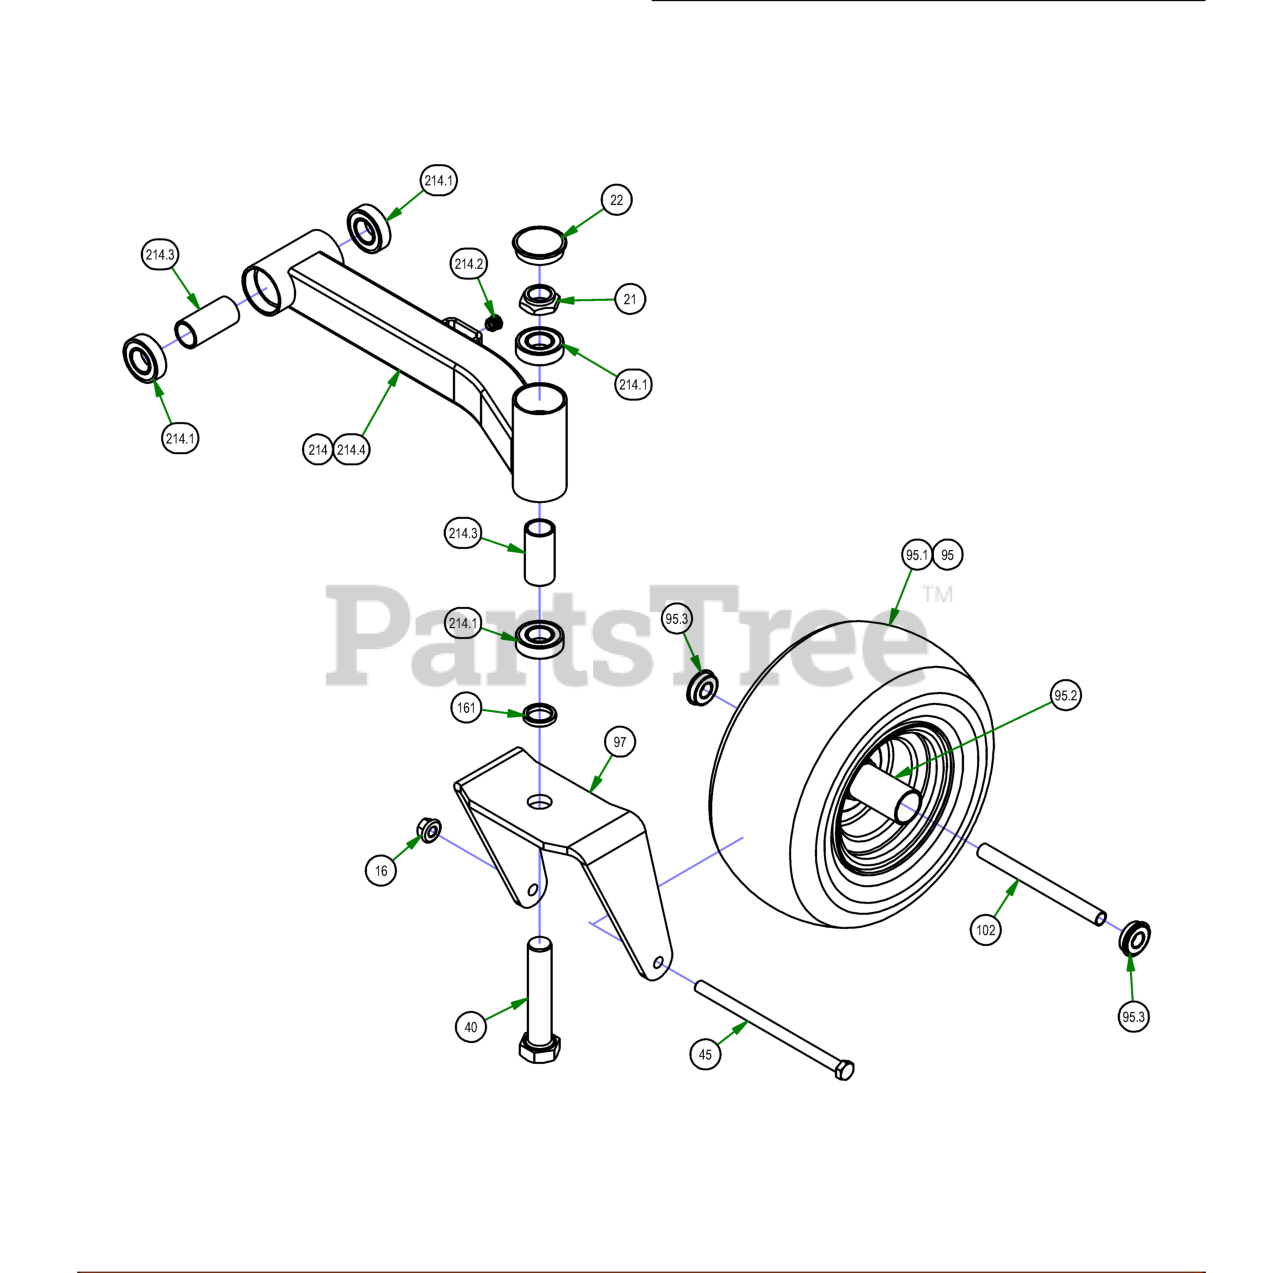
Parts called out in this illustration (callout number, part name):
16	1/2-13 NYLON INSERT FLANGE LOCKNUT ZINC
21	1"-14 NYLON INSERT JAM LOCKNUT ZINC
22	2017 Bearing Cover
40	1"-14 X 5 HEX CAP SCREW (GR.8) ZINC YELLOW
45	1/2-13 X 8-1/2 HEX CAP SCREW (GR.5) ZINC
95	13x6.5-6 Black Tire and Wheel Assembly
95.1	13 x 6.50 - 6 Tire
95.2	Front Tire Rim
95.3	Ball Bearing w/Retainer, 99502H-NR, .625 Bore x 1.375 OD x .4375 Width
97	2017 ZT Front Fork
102	Front Wheel Spanner
161	Spacer, 1x1.375x.25
214	2021 ZT Suspension Arm Assembly Left (48", 54", & 60")
214.1	1641 BEARING W/2 CONTACT RUBBER SEALS
214.2	5/8 Round Insert
214.3	2016 Front Bearing Spacer
214.4	2021 ZT LH Front Arm
